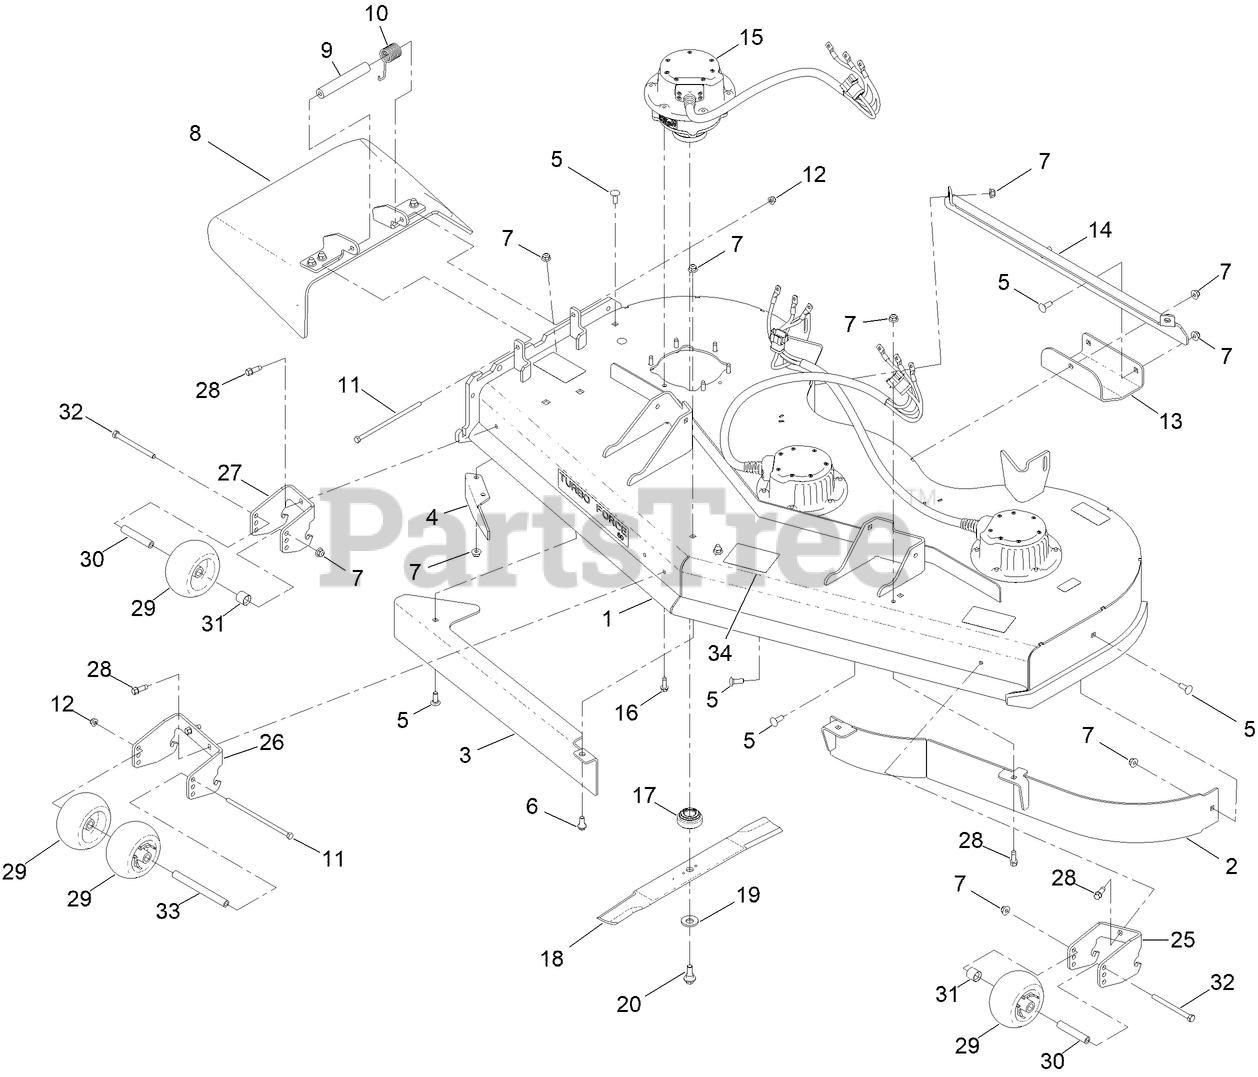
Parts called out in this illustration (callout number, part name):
1	DECK ASM, 60IN
1	SCREW-CARR
2	BAFFLE ASM, 60IN [RED]
2	DEFLECTOR
3	PLATE-BAFFLE, FORMED [RED]
3	STRAP-DISCHARGE
4	BAFFLE-DISCHARGE
4	DEFLECTOR-DECK, RUBBER
5	SCREW-CARR
5	PLATE-HINGE, REAR
6	BOLT-SHOULDER
6	PLATE-HINGE, FRONT
7	NUT-HF, NI
8	RUBBER DEFLECTOR ASM
9	SPACER
10	SPRING-TORSION
11	SCREW-HH
12	NUT-HF, NI
14	BRACKET-SKID
15	MOTOR/GEN-48V,
16	SCREW-THD ROLL, HWH
17	RETAINER-BLADE
18	BLADE-20.5IN, MED SAIL
19	WASHER-BELLEVILLE
20	SCREW-SHOULDER,HWH
25	BRACKET-WHEEL, LH
26	BRACKET-WHEEL, CENTER
27	BRACKET-WHEEL, RH
29	ROLLER-SCALP, ANTI
30	TUBE-SPANNER
31	SPACER-AXLE, REAR
32	SCREW-HH
33	SPACER-WHEEL
34	DECAL-SCALP, ANTI
